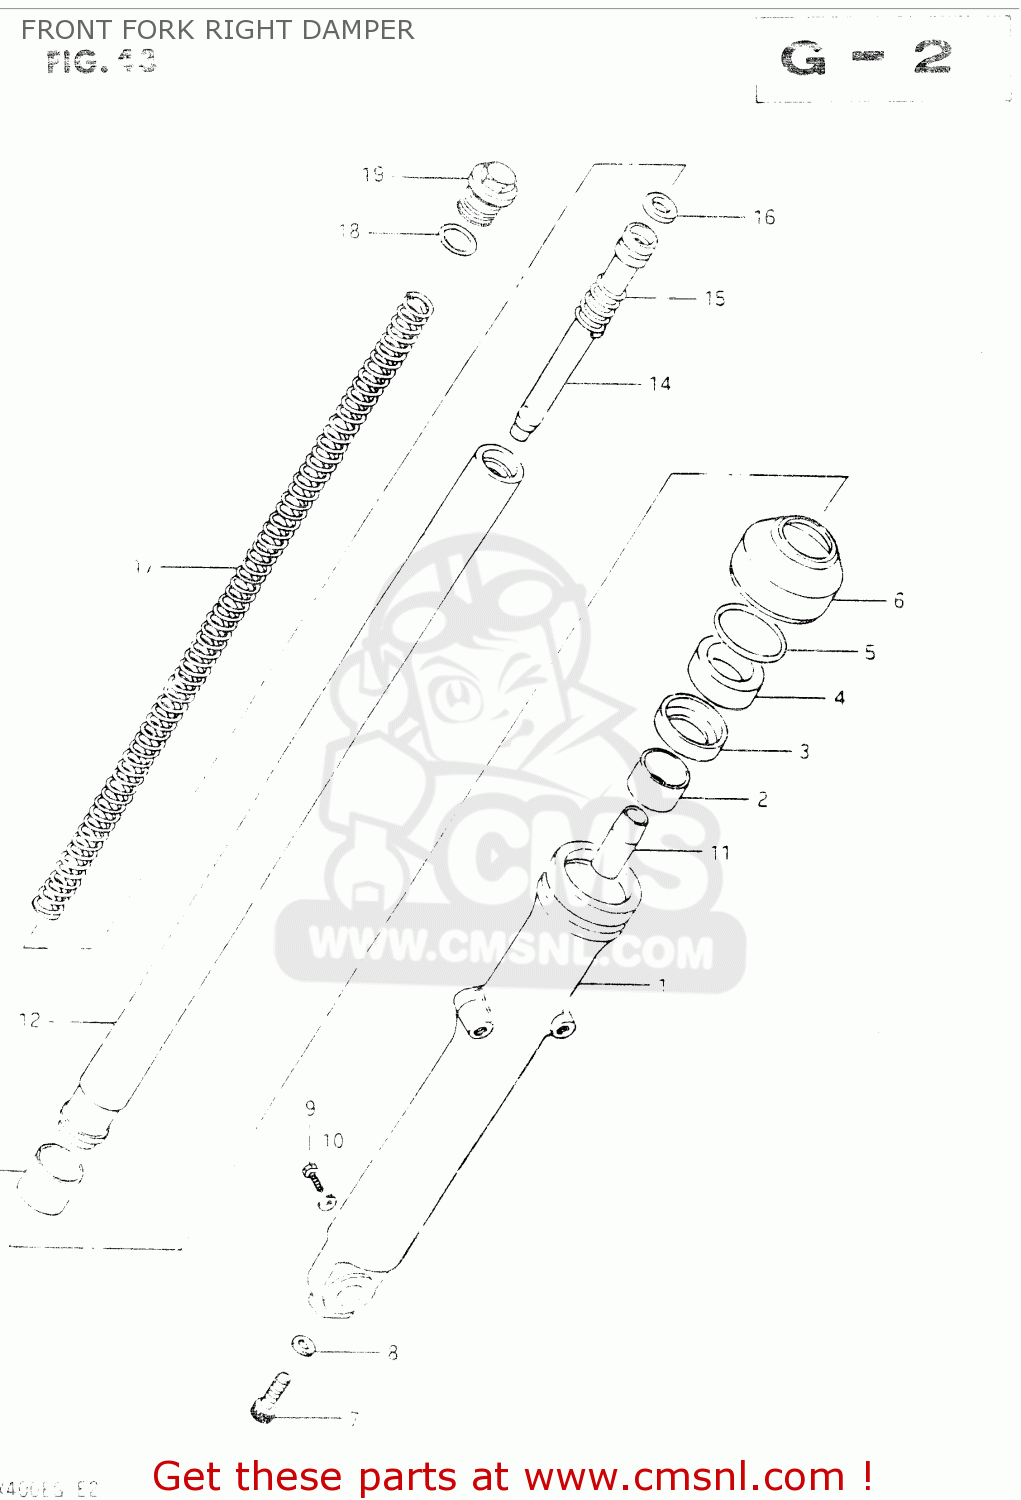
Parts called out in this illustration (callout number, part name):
1	OUTER TUBE RH
2	BUSH,GUIDE
3	SPACER,OIL SEAL
4	OIL SEAL,FRONT FORK
5	CIRCLIP,FORK OIL SEAL
6	DUST SEAL
7	BOLT(8X27)
8	GASKET (NAS)
9	BOLT
10	GASKET,DRAIN,PLUG (NAS)
11	PIECE,OIL LOCK
12	TUBE,INNER
13	BUSH
14	CYLINDER,FRONT FORK
15	SPRING,REBOUND
16	RING,PISTON
17	SPRING,FR.FORK
18	O RING
19	BOLT
